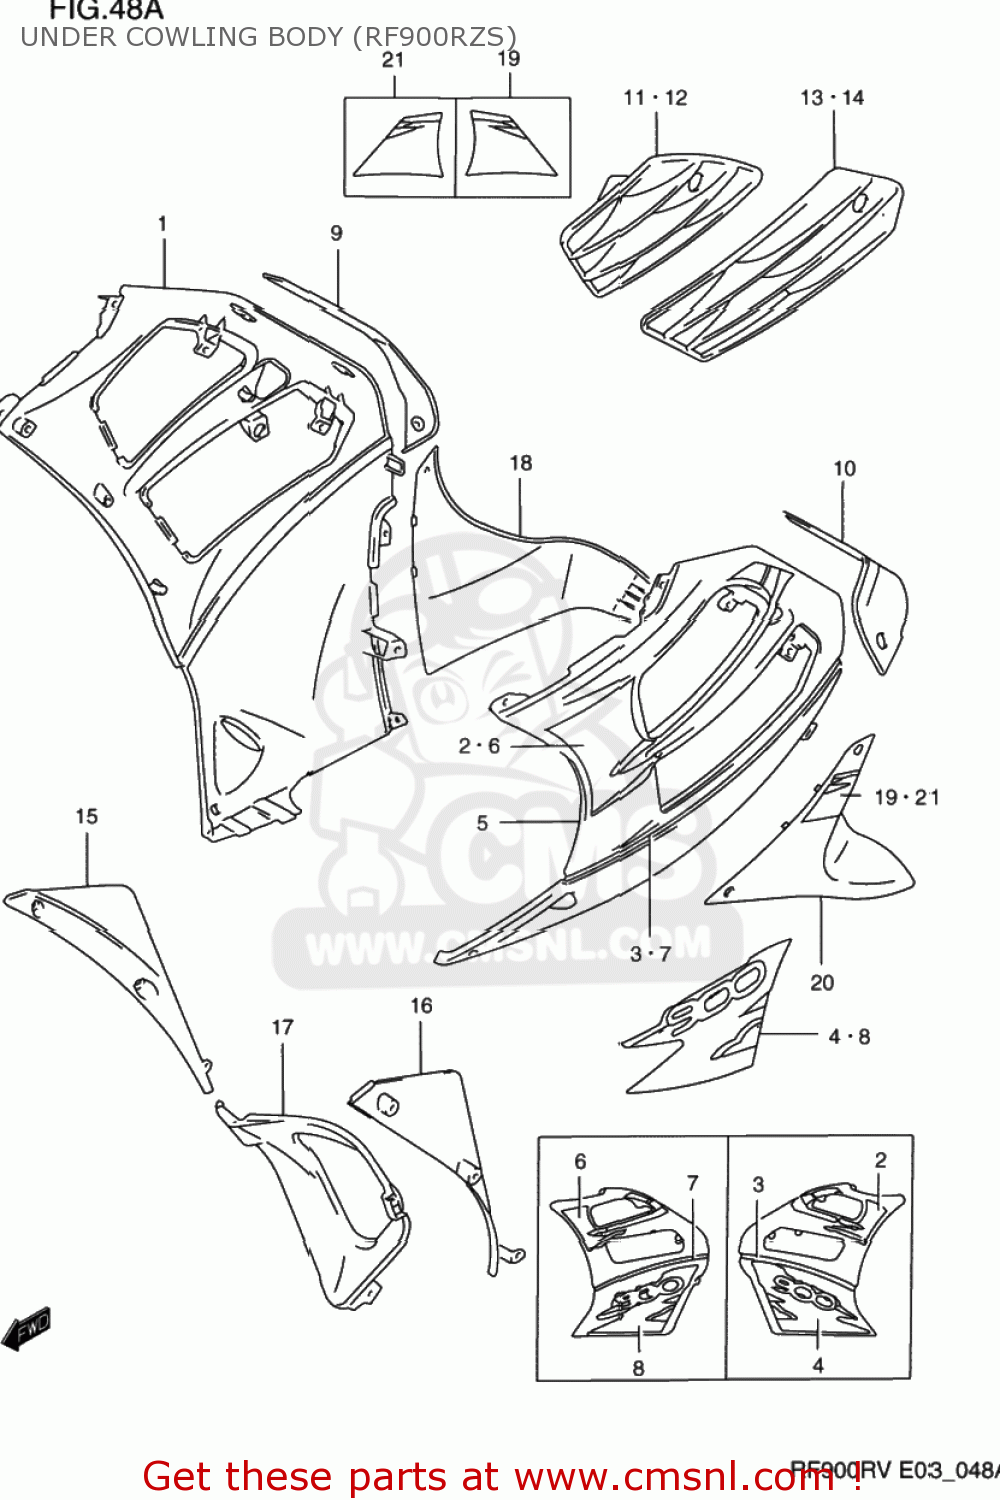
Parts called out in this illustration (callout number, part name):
1	COWLING ASSY,UNDER,R(SILVER)
2	TAPE SET,COWL UNDER UPR,R
3	TAPE,UNDER COWL,R
4	TAPE,COWL UNDER LWR,R
5	COWLING ASSY,UNDER,L(SILVER)
6	TAPE SET,COWL UNDER UPR,L
7	TAPE,UNDER COWL,L
8	TAPE,COWL UNDER LWR,L
9	PANEL,UNDER,R
10	PANEL,UNDER,L
11	COVER,UNDER COWL UPR,R
12	COVER,UNDER COWLING,UPPER,LEFT (
13	COVER,UNDER COWL LWR,R
14	COVER,UNDER COWL LWR,L
15	COWLING,UNDER INNER,R
16	COWLING,UNDER INNER,L
17	COWLING,UNDER CTR
18	COWLING,UNDER RR,R
19	TAPE,COWLING,UNDER,REAR
20	COWLING,UNDER,REAR,LEFT (P
21	TAPE,COWL UNDER RR,L
